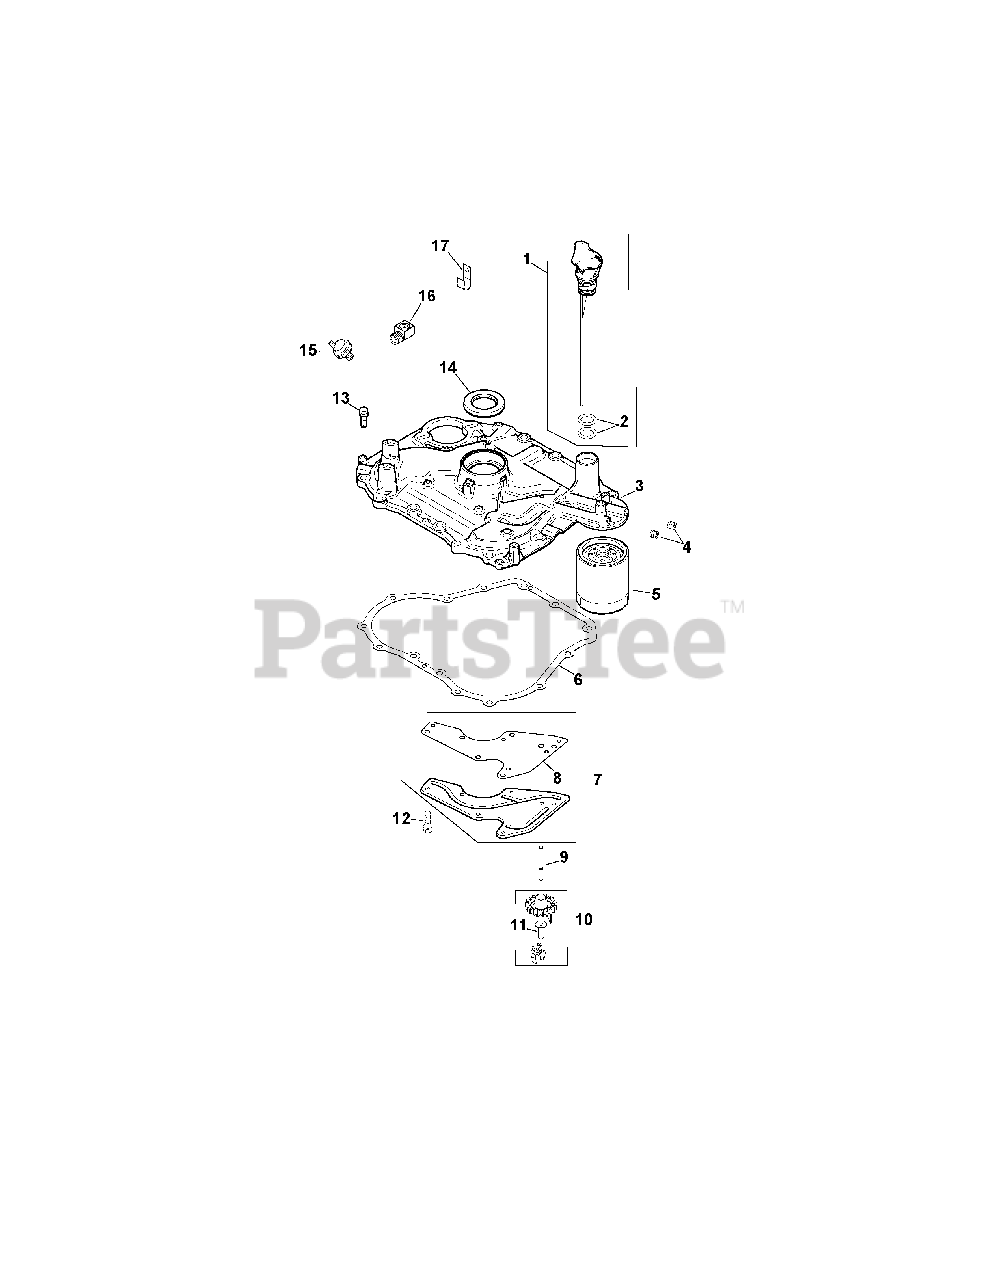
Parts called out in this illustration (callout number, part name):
1	Dipstick Assembly Kit
2	Dipstick O-Ring
3	Closure Plate Assembly
5	Oil Filter
6	Closure Plate Gasket
7	Oil Passage Cover Kit
8	Oil Passage Gasket
9	Governor Gear Shaft
10	Gear & Weight Assembly
11	Governor Regulating Pin
12	Hex Flange Screw (M5 x .8 x 13)
13	Hex Flange Screw (M8 x 1.25 x 30)
14	Oil Seal
15	Pressure Switch
16	1/8" N.P.T.F. Elbow
